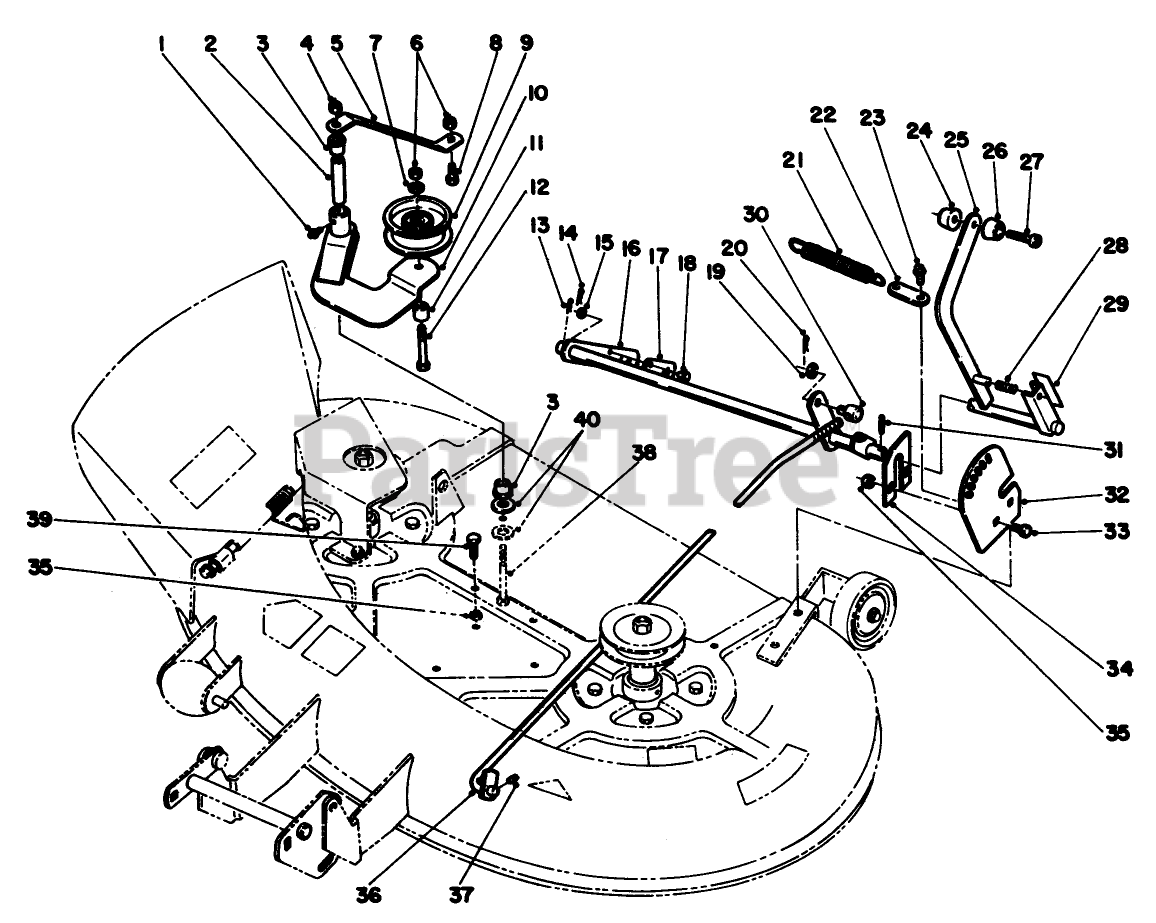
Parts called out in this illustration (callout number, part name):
1	FITTING-GREASE
2	SPACER
3	BUSHING
4	NUT-LOCK, NI
5	BRACE R
6	NUT-LOCK, NI
7	WASHER-FLAT
8	BOLT-CARR
9	PULLEY-IDLER
10	WLDMT-IDLER ARM R
11	SPACER
12	SCREW-HH
13	PIN-COTTER
14	PIN-COTTER
15	Washer
16	WLDMT-HEIGHT ADJ R
17	LATCH B
19	WASHER-FLAT
20	Hairpin Cotter
21	SPRING-EXTENSION
22	Lever
23	Bolt
24	KNOB
25	WLDMT-LIFT LEVER R
26	KNOB
27	BOLT-4
28	SPRING-COMPRESSION
29	DECAL-HOC
30	STUD-TRUNION
31	PIN-SPIROL
32	QUADRANT R
33	BOLT-CARR
34	PLATE-RETAINING R
35	NUT-LOCK, NI
36	WLDMT-HEIGHT ADJ R
37	PIN-SPRING
38	SCREW-HH
39	SCREW-HH
40	WASHER
